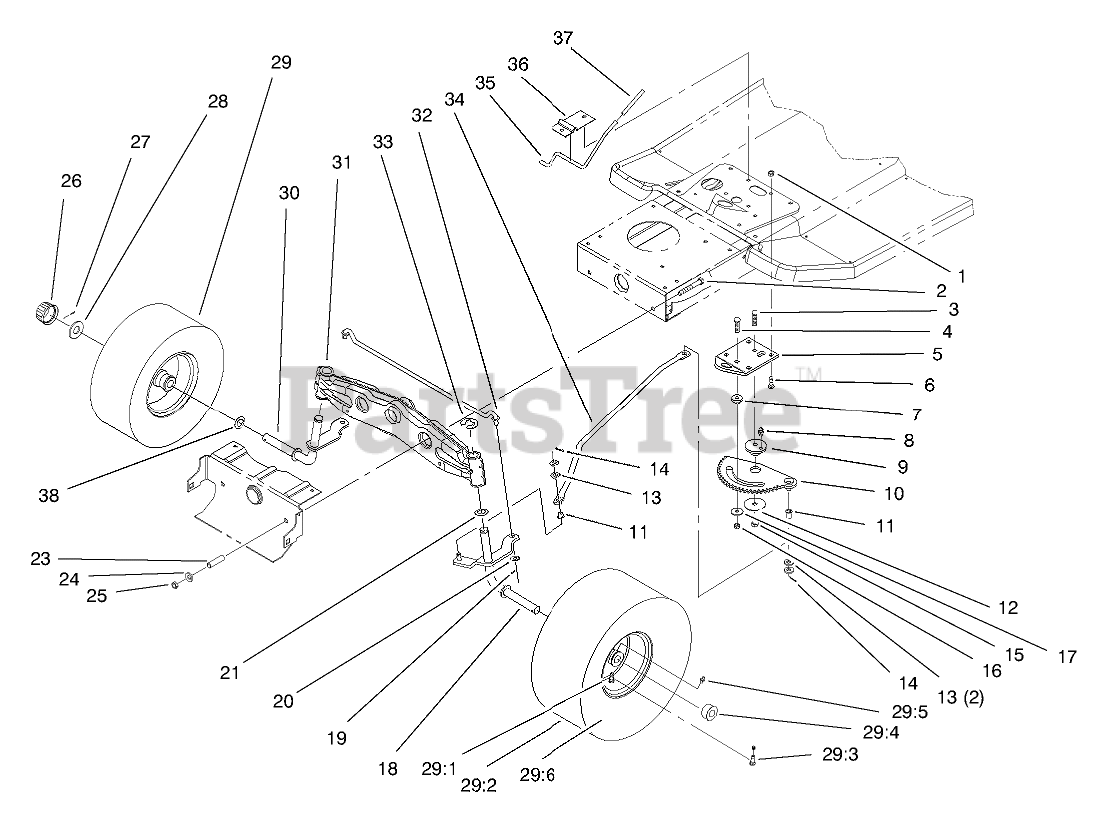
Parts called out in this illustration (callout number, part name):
1	NUT-LOCK, NI
2	SCREW-HH
3	SCREW-CARR
4	SCREW-CARR
5	BRACKET-RACK, STEERING
6	BOLT-CARR
7	SPACER-RACK, STEERING
8	FITTING-GREASE
9	BUSHING-ECCENTRIC
10	RACK-STEERING
11	BUSHING-FLANGED, NYLON
12	WASHER-BEARING
13	WASHER-FLAT
14	PIN-COTTER
15	NUT-LOCK, NI
16	NUT-LOCK, NI
17	WASHER-PIVOT
18	LH SPINDLE ASM
19	PIN-COTTER
20	WASHER-FLAT
21	WASHER-THRUST
23	SPACER
24	WASHER-FLAT
25	NUT-LOCK, NI
26	CAP-HUB
27	PIN-COTTER
28	WASHER-PLAIN
29	Front Wheel & Tire ASM
29:1	RIM ASM
29:2	TIRE 13 X 5.00 X 6
29:3	STEM-VALVE
29:4	BEARING-WHEEL
29:5	FITTING-GREASE
29:6	Inner Tube
30	RH SPINDLE ASM
31	FRONT AXLE ASM
32	TIE ROD-STEERING
33	E-RING
34	LINK-DRAG
35	ROD-BRAKE, PARKING
36	BRACKET-PARKING BRAKE
37	GRIP-BRAKE, PARKING
38	WASHER-THRUST
